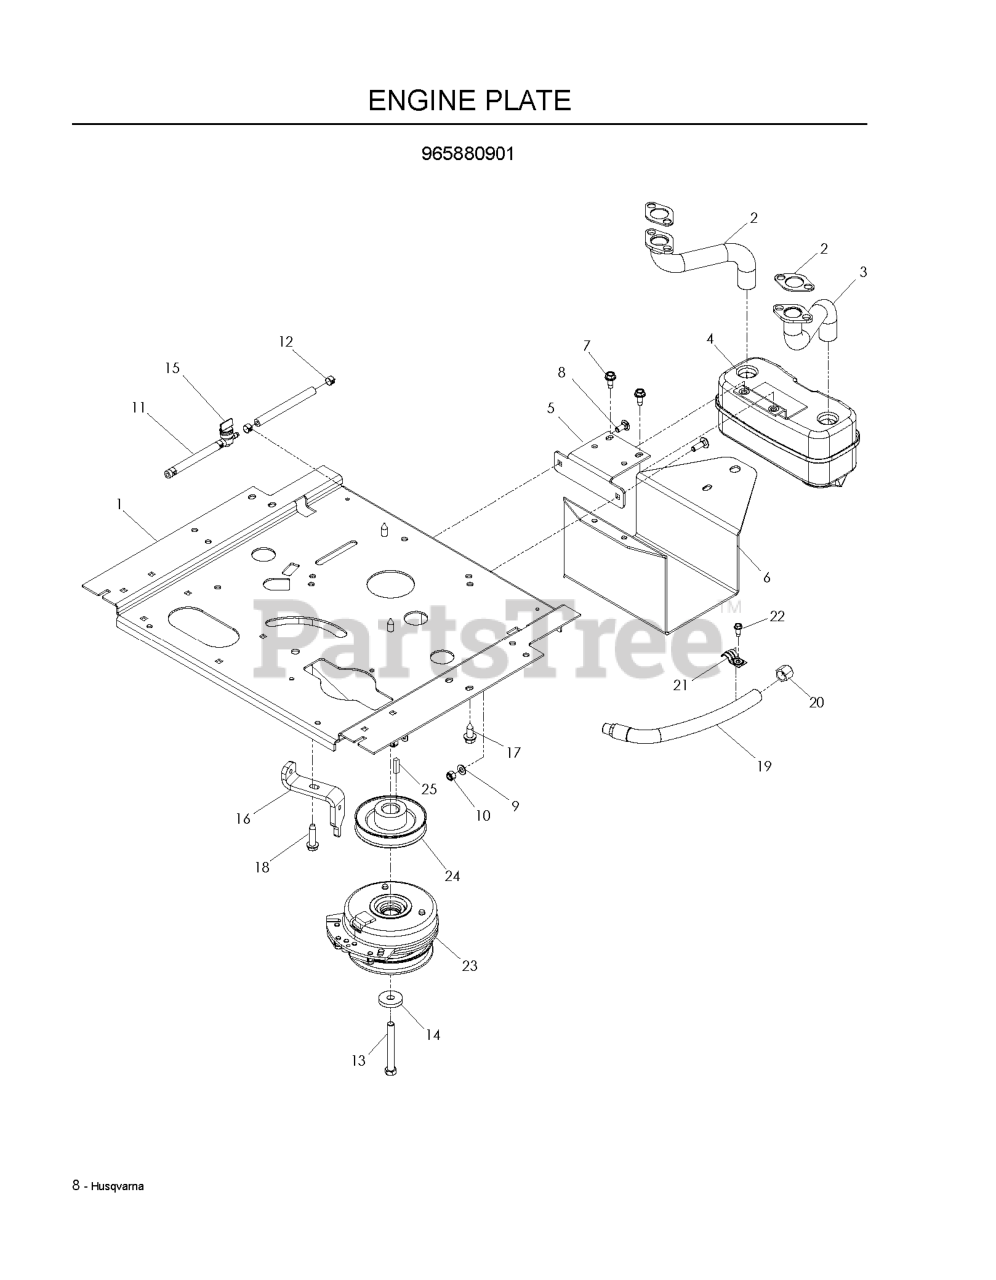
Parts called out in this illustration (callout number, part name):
1	PLATE, ENGINE, BLACK
2	RP.PIPE-EXHAUST LH
3	RP.PIPE-EXHAUST RH
4	MUFFLER ASM TWIN
5	BRACKET, MUFFLER, BLACK
6	GUARD, MUFFLER, BLACK
7	BOLT 5/16-18 X 3/4
8	BOLT 5/16C X 3/4" CARRIAGE
9	FLAT WASHER 5/16 SAE
10	NUT 5/16 NYLOC
11	FUEL LINE 5"
12	HOSE CLAMP
13	HCS 7/16-20X3-1/2 GR 5 ZN
14	CLUTCH, WASHER
15	FUEL VALVE
16	STOP, CLUTCH BLK
17	HHFS 3/8-16 X 1.0 THD FORMING
18	BOLT 3/8-16 X 1 1/2 ZINC CLEAR
19	OIL DRAIN HOSE
22	SCREW 1/4 X 5/8
23	CLUTCH, 105 FT-LBS
25	KEY 1/4 SQ X 1.0
26	WASHER 7/16 LOCK
27	EXHAUST GASKET - KAW
